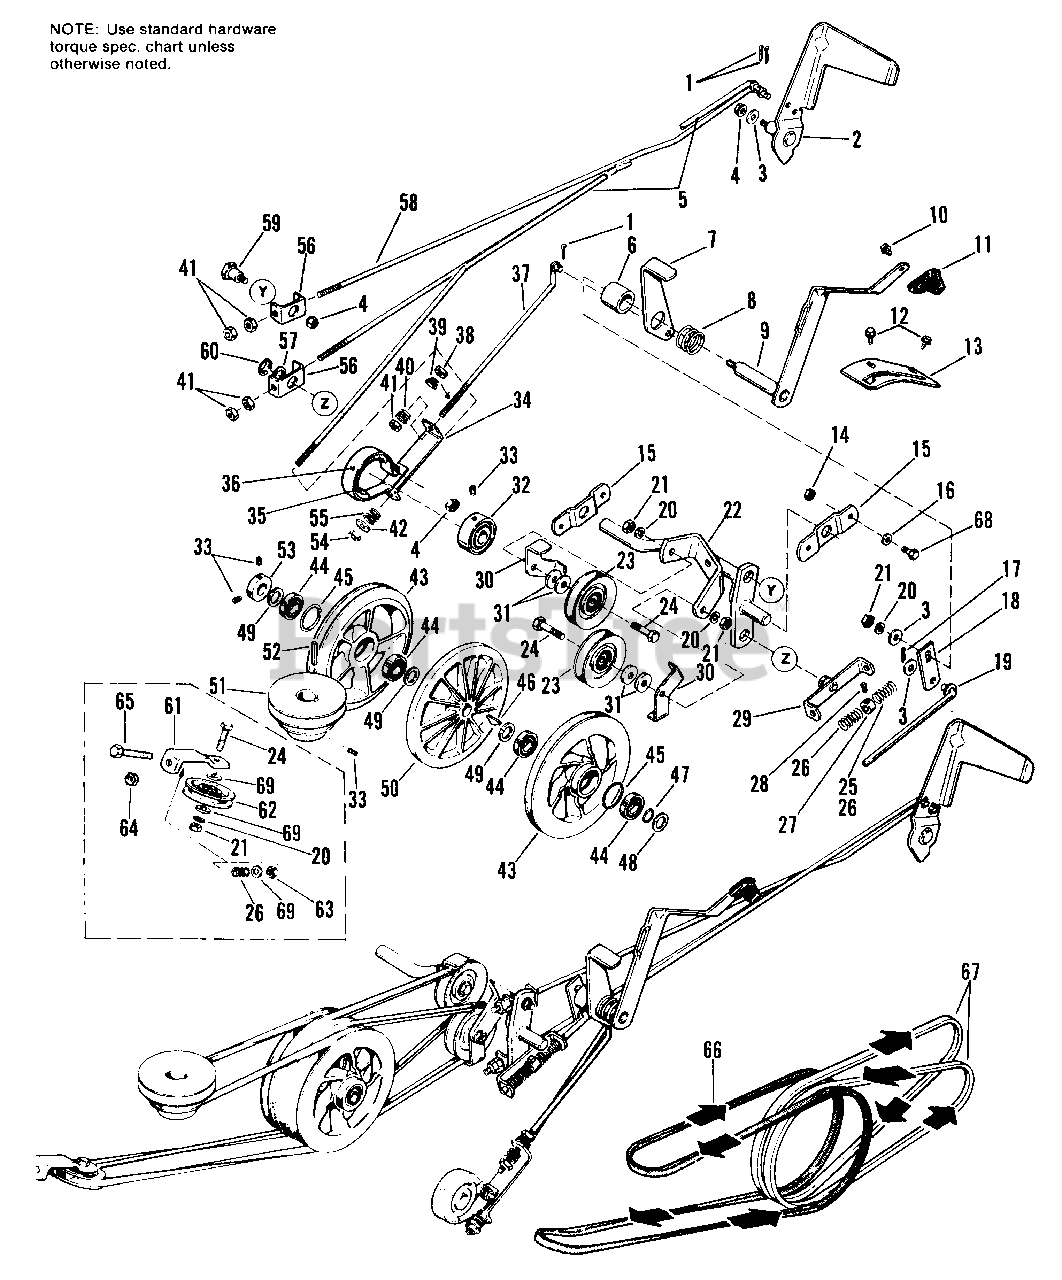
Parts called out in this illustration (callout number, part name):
1	PIN, Cotter, 3/32 x 3/4
2	PEDAL ASSY., Foot
3	WASHER, Plain, 3/8
4	LOCKNUT, Flange, 3/8-16
5	ROD, Brake
9	LEVER ASSY., Control
10	SCREW. Thd. Forming, 1/4-20 x 7/8
12	SCREW, Swage Form, 5/16-18 x 1/2
14	NUT, Flange, 1/4-20
15	SUPPORT, Pivot
16	WASHER, Plain, 1/4
17	PIN, Cotter, 1/8 x 1
19	ROD, Clutch
20	LOCKWASHER, 3/8
21	NUT, Hex, Full, 3/8-16
22	BRACKET, Pivot
23	PULLEY, Idler
24	CAPSCREW, Hex Hd., 3/8-16 x 1-1/2
25	SPRING
26	SPRING (Qty. 2 used on 990963)
27	COLLAR, Set
28	SETSCREW, 1/4-20 x 3/8
29	GUIDE ASSY., Rod
30	GUIDE, Belt
31	WASHER, Special
32	DRUM, Brake
33	SETSCREW, 5/16-18 x 5/16
34	BAND ASSY., Brake
35	LINING, Brake
36	RIVET, #7 x 1/4
37	ROD, Parking Brake
38	LOCKNUT, Elastic, 5/16-18
41	NUT, Hex, Full, 5/16-18
42	WASHER, Plain
43	PULLEY ASSY., Outer
45	RING, Retaining
47	RING, Retaining
50	CLUTCH, Center Disc
51	PULLEY, Engine
53	COLLAR, Set
54	LOCKNUT, Hex, 5/16-18
56	GUIDE, Rod
58	ROD ASSY., Clutch
59	BOLT, Shoulder
60	RING, Retaining
61	BRACKET, Idler
62	PULLEY, Idler
63	LOCKNUT, Elastic, 3/8-16
64	LOCKNUT, Hex, 3/8-16
65	CAPSCREW, Hex Hd., 3/8-16 x 4
67	BELTS, Matched
68	CAPSCREW, Hex Hd., 1/4-20 x 3/4
69	WASHER, Plain, 5/16
